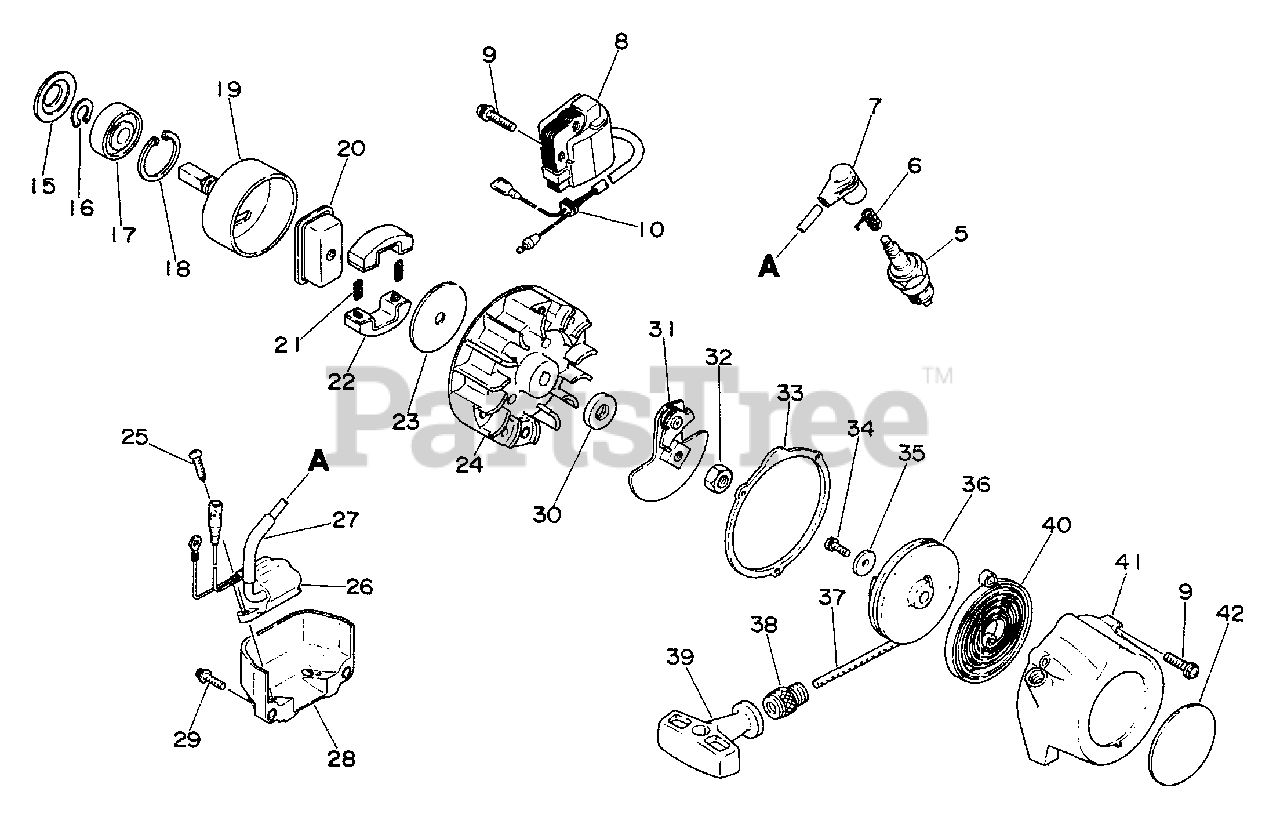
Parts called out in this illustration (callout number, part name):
5	SPARK PLUG -- CJ-8
6	TERMINAL, SPARK PLUG CAP
7	CAP, SPARK PLUG
8	COIL, IGNITION
9	SCREW - 4X20
15	RETAINER, PIPE
16	RING, RETAINING - 12
17	BEARING, BALL - 6201
18	RING, RETAINING - 32
19	DRUM, CLUTCH
20	HUB, CLUTCH
21	SPRING, CLUTCH
22	SHOE, CLUTCH
23	PLATE, CLUTCH
24	FLYWHEEL
25	SCREW - 4X16 -- TAPPING
26	COIL, IGNITION
27	TUBE
28	COVER
29	SCREW - 4X14
31	STARTER PAWL ASSY
33	GASKET, STARTER
34	SCREW - 4X10
36	REEL, ROPE
37	ROPE, STARTER - 3X850
38	GUIDE, ROPE
39	GRIP, STARTER
40	SPRING, REWIND
41	CASE, STARTER
42	LABEL - ECHO
